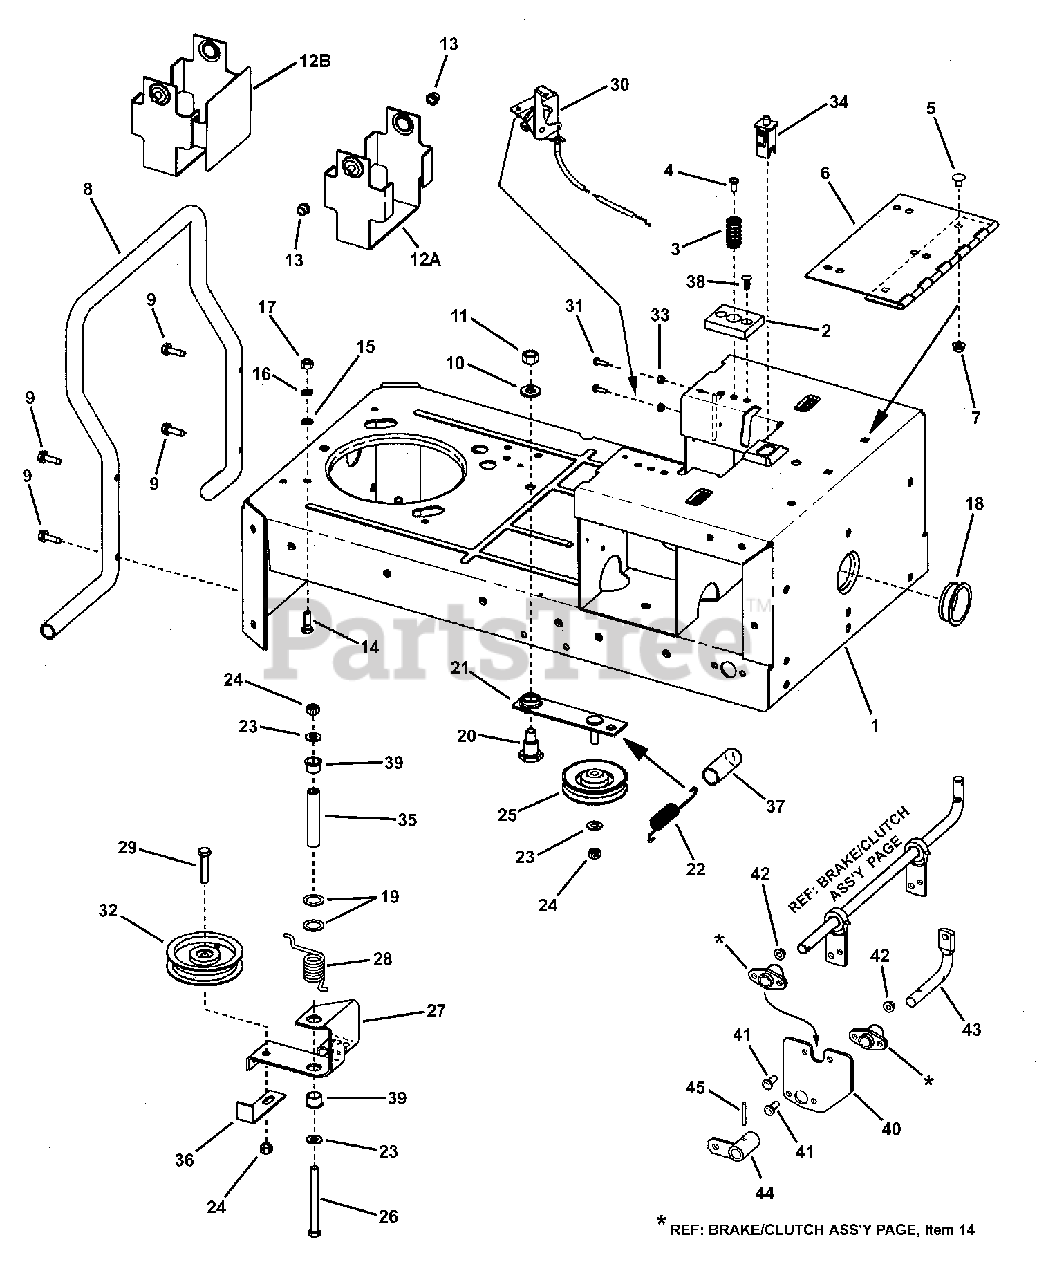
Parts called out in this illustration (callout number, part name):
1	WELDMENT, Rear Frame
2	CUSHION, Seat Support
3	SPRING, Seat Support
4	SCREW, 1/4-20 x 5/8" Pan Head Self-Tap (Torx)
5	BOLT, 5/16-18 x 1/2" Short Neck Carriage, GR 5
6	HINGE, Seat
7	NUT, 5/16-18 Hex Flange Lock, GR 5
8	BUMPER, Rear
9	SCREW, 5/16-18 x 1-1/2" Hex Washer Self-Tap
10	WASHER, .531 x 1.062 x .121 SAE Flat
11	NUT, 1/2-13 Hex Center Lock, GR 5 or B
12A	WELDMENT, Battery Bracket
12B	WELDMENT, Battery Bracket
13	BUSHING, Tie Rod
14	SCREW, 5/16-24 x 1" Hex Head Cap, GR 5
15	RETAINER, 5/16" Bolt
16	WASHER, .32 x .58 x .08 Split Lock
17	NUT, 5/16-24 Hex, GR 5 or B
18	GROMMET
19	WASHER, 3/4" Flat
20	BOLT, 1/2-13 Hex Shoulder
21	WELDMENT, Idler Arm, Primary
22	SPRING, Extension- 5" long
23	WASHER, 3/8" SAE Flat
24	NUT, 3/8-16 Hex Center Lock, GR 5 or B
25	PULLEY, Idler, V 3.30 HA
26	BOLT, 3/8-16 x 4" Hex Head Cap, GR 5
27	BRACKET, Hydro Idler
28	SPRING, Hydro Idler
29	SCREW, 3/8-16 x 1-3/4" Hex Head Cap, GR 5
30	CABLE, Hydro Release Valve
31	SCREW, #10-32 x 5/8" Hex Washer Head Machine
32	IDLER, 4.12" Outside Diameter, Flat
33	NUT, #10-32 Hex Nyloc
34	SWITCH, Seat (NO/NC) Snap-In
35	SLEEVE, Idler
36	GUIDE, Belt
37	COVER, Spring
38	FASTENER, Ratchet
39	BUSHING, Flange, .64 x .75 x .5
40	PLATE, Pivot
41	SCREW, 5/16-18 x 7/8" Pan Head Self-Tap (Torx)
42	NUT, 5/16-18 Hex Flange Lock, GR 5
43	WIREFORM, Control
44	WELDMENT, Bellcrank
45	PIN, 3/16 x 1-1/2" Roll
